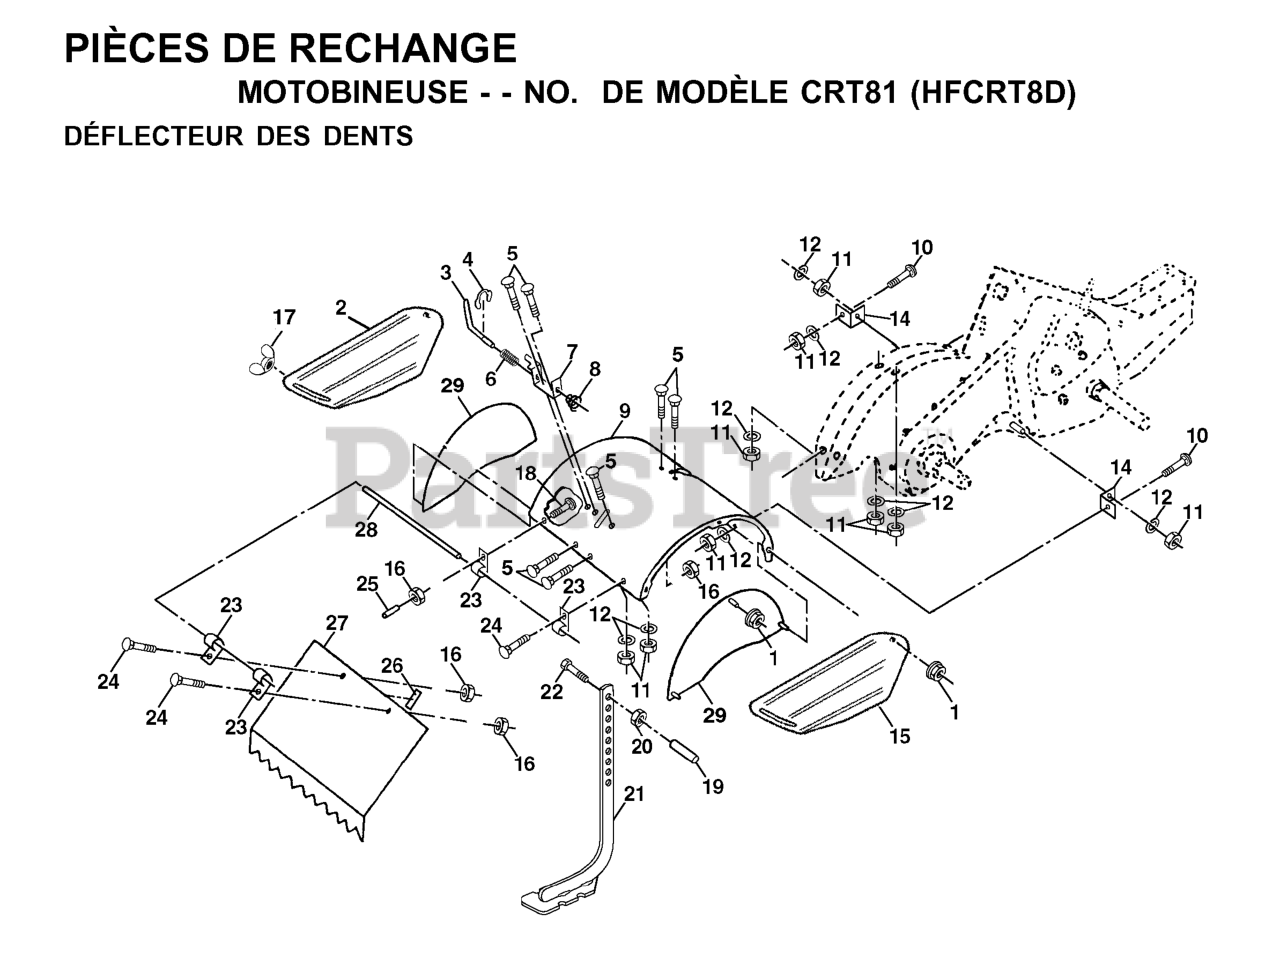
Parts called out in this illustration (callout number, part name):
1	NUT LOCK HEX FLANGE 5/16-18
2	TINE SHIELD
3	STAKE PIN TI
4	KLIP RING TI
7	BRACKET.LATCH.STAKE.3.20.BLACK
8	SPRING CRT
9	SHIELD TINE
10	RP BOLT 5/16-18 X3/4 ZN/YEL GR
12	WASHER.LOCK.HVY.HLCL.SPR.5/16
14	BRACKET, TINE SHIELD
15	SHIELD
16	NUT T
20	NUT.HEX.3/8-16UNC
21	STAKE.ASM.DEPTH
22	BOLT.375-16
25	VINYL CAP TI
26	PAD IDLER TI
27	SHIELD.LEVELING.21".ORANGE
28	PIN, HINGE
29	SHIELD, SIDE
32	NUT
33	LOCKWASHER
